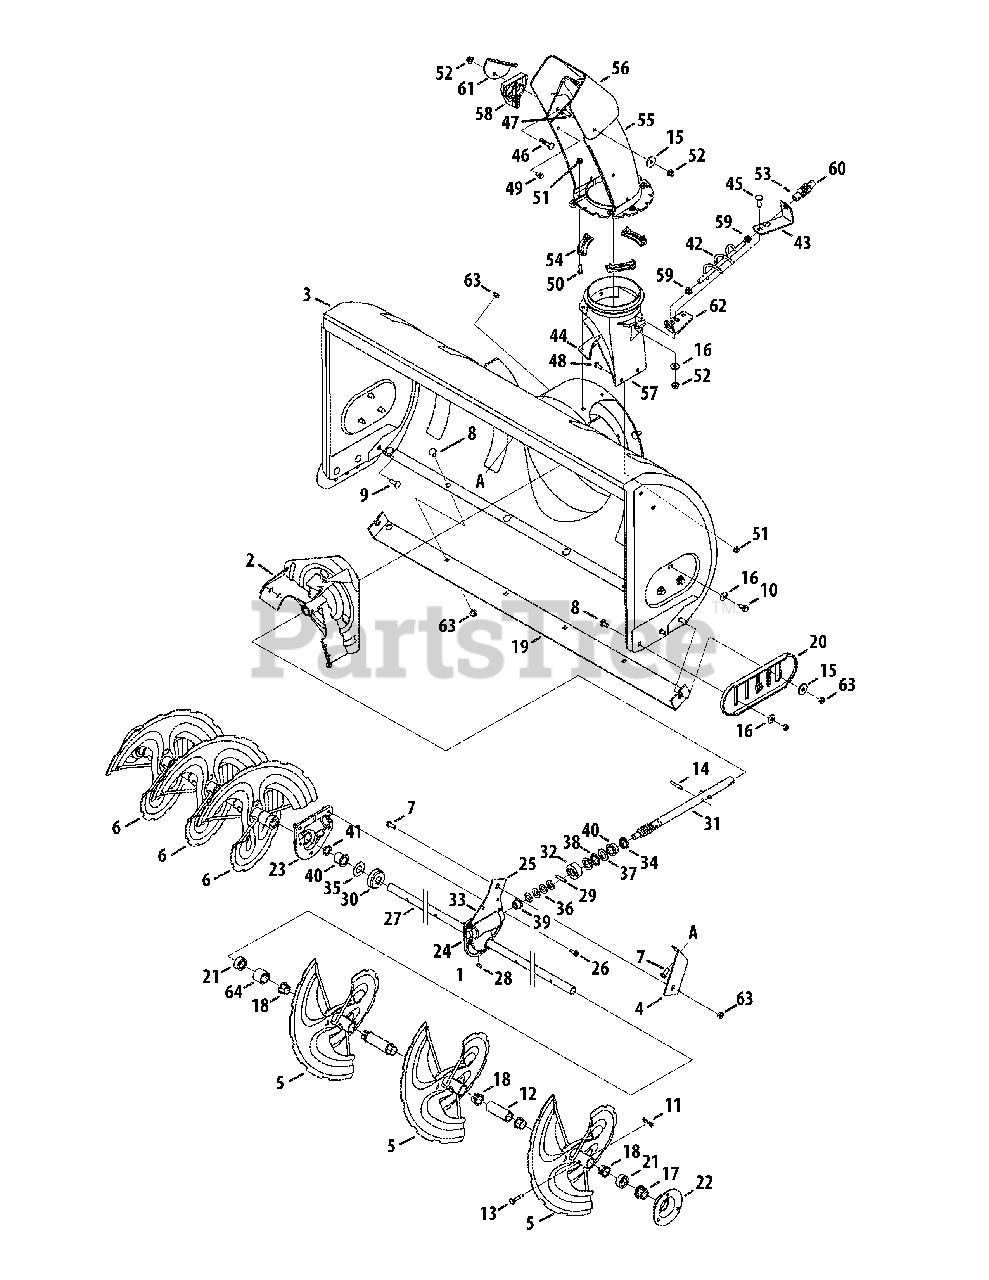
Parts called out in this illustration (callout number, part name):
1	Auger Gear Box (Incl. Ref. 23-41)
2	Impeller Assembly, 12"
3	Housing Assembly
4	Housing Brace Bracket
5	LH Spiral Auger
6	RH Spiral Auger
7	Hex Cap Screw, 5/16-18 x .625
8	Carriage Bolt, 5/16-18 x .62
9	Splined Carriage Screw
10	SCREW 5/16-18 x .750
11	Bow-Tie Cotter Pin
12	Sleeve .758 x 1.00 x 2.70
13	Shear Pin, .25 x 1.50
14	Spirol Pin, 1/4 x 1-1/2
15	Flat Washer, .344 x 1.125 x .12
16	Bell Washer, .340 x .872
17	Hex Flange Bearing, .75 ID
18	Flange Bushing, .80 x .91
19	Skid Plate Bracket, 42"
20	Slide Shoe
21	Spacer, .75 x .125 x .5
22	Hex Bearing Housing, 1.0
23	RH Reducer Housing
24	LH Reducer Housing
25	Housing Brace Plate
26	Self Tapping Screw, 1/4-20 x .75
27	Spiral Axle, 41.5"
28	Hi-Pro Key, 3/16 x 5/8
29	Spring Spirol Pin, .25 x 1.25
30	Worm Gear, 20-tooth
31	Worm Shaft
32	Thrust Collar
33	Grease Plug
34	Grease Seal
35	Flat Washer, .76 x 1.5 x .030
36	Flat Washer, .508 x 1.0 x .020
37	Thrust Washer, .75 x 1.25 x .0615
38	Thrust Bearing, .75 x 1.25 x .078
39	Flange Bearing, .503 x .75
40	Flange Bearing, .75 x 1.0 x .59
41	Grease Seal
42	Chute Crank Assembly
43	Chute Crank Bracket
44	Chute Reinforcer
45	Splined Carriage Screw
46	Carriage Bolt, 5/16-18 x 1.5
47	Carriage Screw, 5/16-18 x 1.0
48	Screw, 1/4-20 x .75
49	Hex Index Washer Screw
50	SCREW 1/4-20 X1.00 GR5
51	Nylon Hex Lock Nut, 1/4-20
52	Nylon Hex Lock Nut, 5/16-18
53	Spirol Pin, .156 x .875
54	Chute Flange Keeper
55	Lower Chute
56	Upper Chute
57	Adapter Chute
58	Chute Tilt Cable Guide
59	Plastic Bushing
60	Joint Block Assembly
61	Cable Bracket
62	Chute Crank Bracket
63	HEX FLANGE NUT
64	Spacer 1.25 x .75 x 1.00
